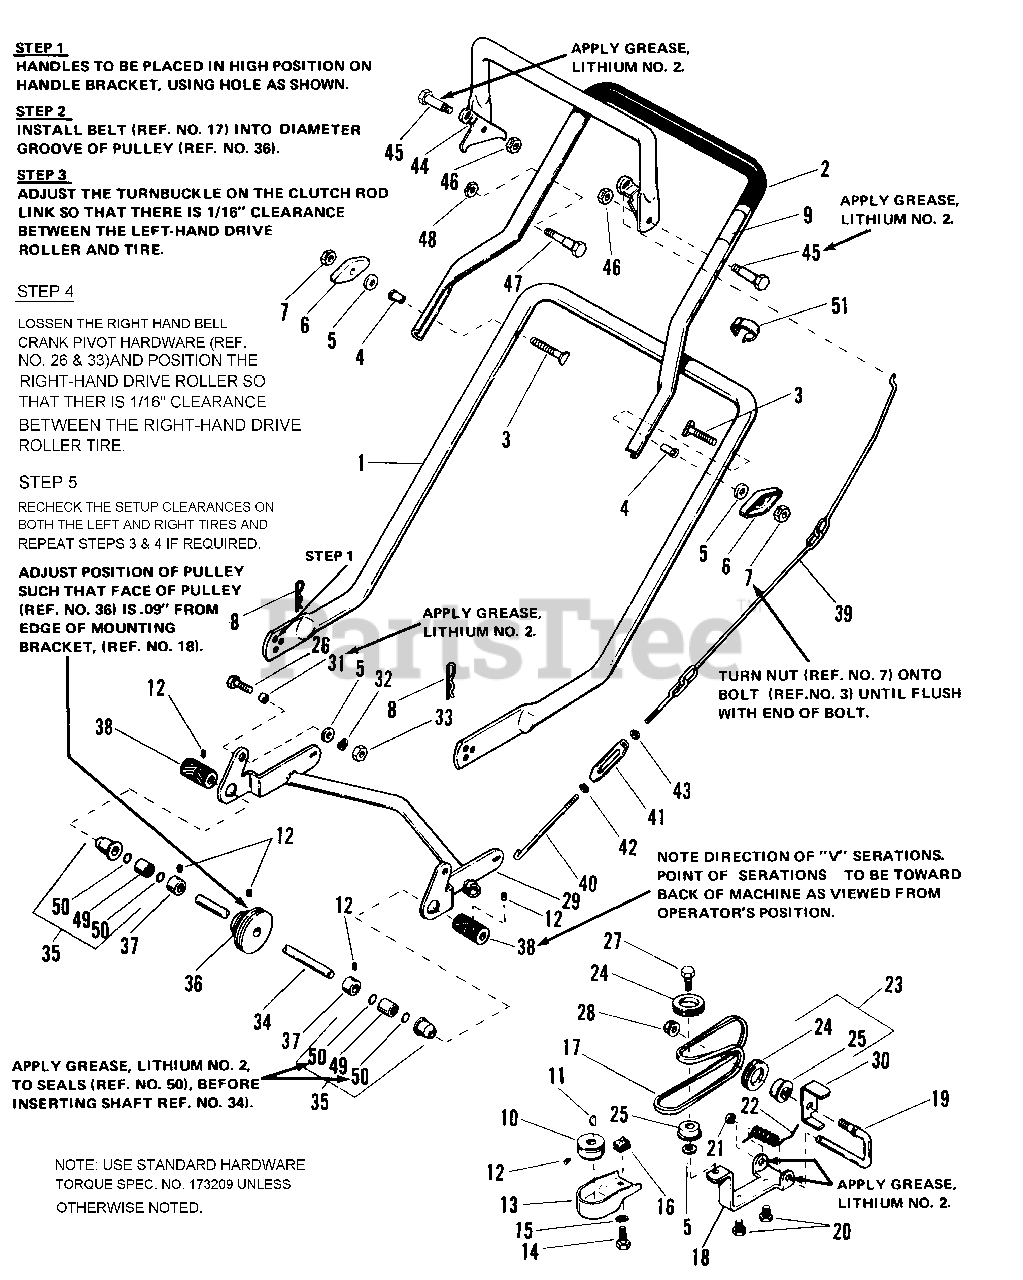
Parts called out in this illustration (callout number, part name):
1	HANDLE, Lower
2	HANDLE, Upper
3	BOLT, Curved Hd.
5	WASHER, Plain
6	NUT, Wing
7	LOCKNUT, Hex, Full, 5/16-18
8	CLIP, Spring
9	DECAL, Handle
10	PULLEY, Engine
11	KEY, Woodruff No. 5
12	SETSCREW, 5/16-18 x 1/4
13	COVER, Pulley
14	CAPSCREW, Hex, 1/4-20 x 1/2
15	LOCKWASHER, 1/4
16	NUT, Tinn., 1/4-20
18	BRACKET, Idler Support
20	SCREW, Taptite
21	RING, Retaining
22	SPRING, Idler
23	PULLEY ASSY (Inc. Ref. Nos. 24, 25)
24	PULLEY, Idler
25	BEARING, Idler
26	SCREW, Special, 5/16-18 x 1
27	SCREW, Taptite, 1/4-20 x 1
28	LOCKNUT, Flange, 1/4-20
29	BELLCRANK ASSY
32	LOCKWASHER, 5/16
33	NUT, Hex, Full, 5/16-18
34	SHAFT, Driver
35	BEARING & RETAINER ASSY
36	PULLEY, Drive
37	COLLAR, Set
38	DRIVER, Wheel
39	ROD, Clutch
40	ROD, Engaging, Lower
42	NUT, Hex, Full, No. 10-24
43	NUT, Hex, Full, No. 10-24
44	HANDLE ASSY, Engaging
45	BOLT, Shoulder
46	LOCKNUT, Hex Jam, 5/16-18
47	STOP, Handle
48	LOCKNUT, Hex, Flange, 5/16-18
49	BEARING, Needle
50	SEAL, Grease
